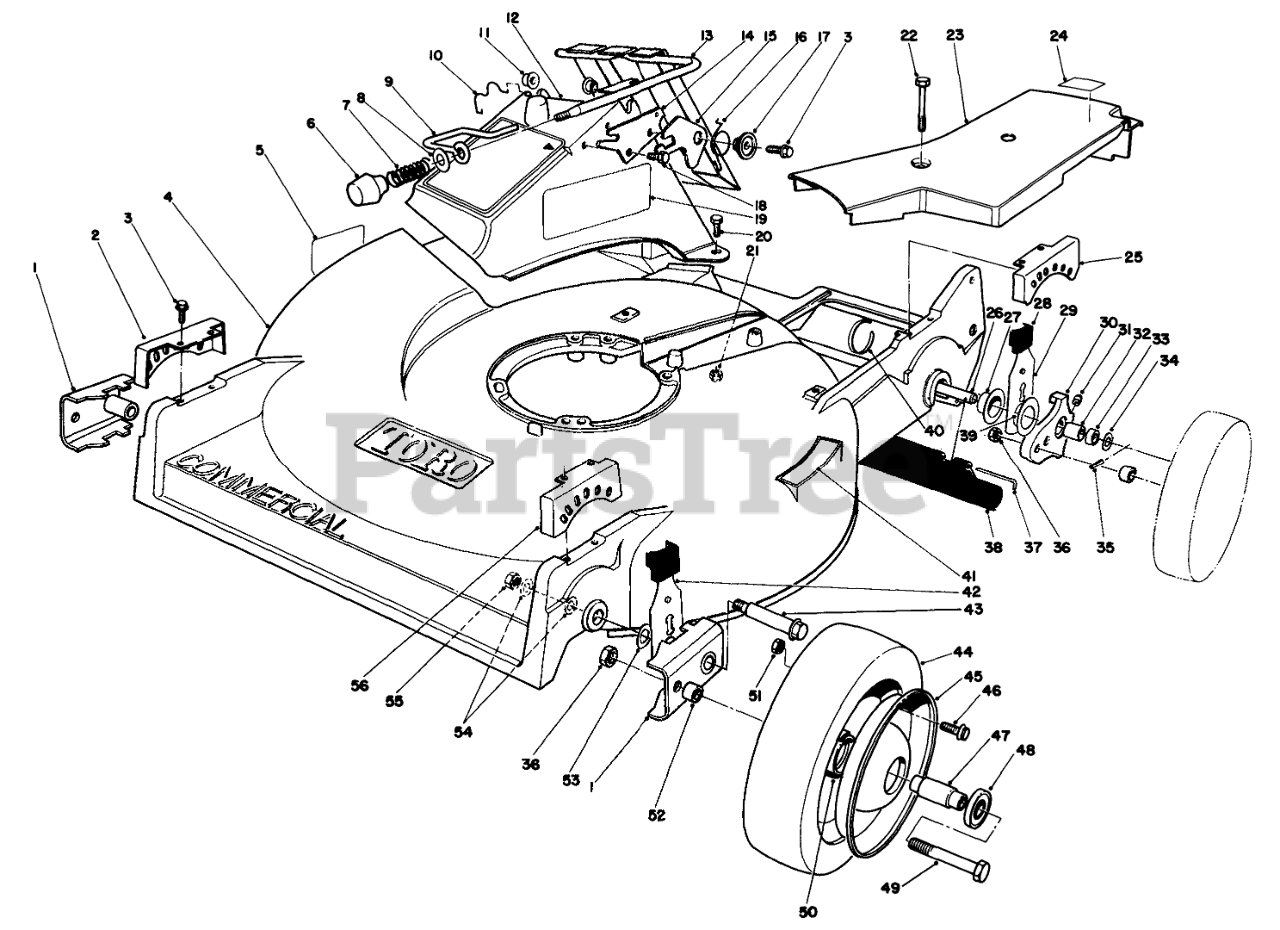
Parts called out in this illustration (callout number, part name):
1	ARM-PIVOT, FRONT
2	QUADRANT-FRONT, RH
3	SCREW-HWHTF
4	Housing-Commercial (Incl. Ref. #5,41)
5	DECAL-DANGER
7	COMPRESSION SPRING
8	WASHER-FLAT
9	DOOR LATCH
10	DOOR RETAINER
11	BUSHING-NYLON
12	DISCHARGE CHUTE B
13	DOOR & HANDLE WA
14	DOOR LATCH PLATE
15	SAFETY LATCH
16	TORSION SPRING
17	DOOR SPACER
18	SCREW-HWH
19	DECAL SAF INST
20	SCREW-HH
21	NUT-LOCK, NI
22	SCREW-HHFTF
23	COVER-BELT
24	LABEL-GREASE, HP
25	QUADRANT-REAR, LH
26	SHAFT-AXLE, REAR
27	CAP-END
28	KNOB-ARM
29	REAR SPRING ARM ASM
30	Pivot Arm (Incl. Ref. #31-33)
31	FITTING-GREASE
32	BUSHING
33	BUSHING
34	WASHER-PLAIN
35	PIN-SPIROL
36	NUT-LOCK, CONE
37	ROD-SHIELD
38	SHIELD-TRAILING
39	WASHER
40	TIE-CABLE
41	STEP PAD DECAL
42	FRONT SPRING ARM ASM
43	WHEEL BOLT
45	Wheel-Half
46	SCREW-HHF
47	SPACER-BEARING
48	BEARING-WHEEL
49	SCREW-HH
50	HUB-BEARING
51	NUT-LOCK, NI
52	SPACER-WHEEL
53	WASHER-THRUST
54	WASHER
55	Nut
56	QUADRANT-FRONT, LH
